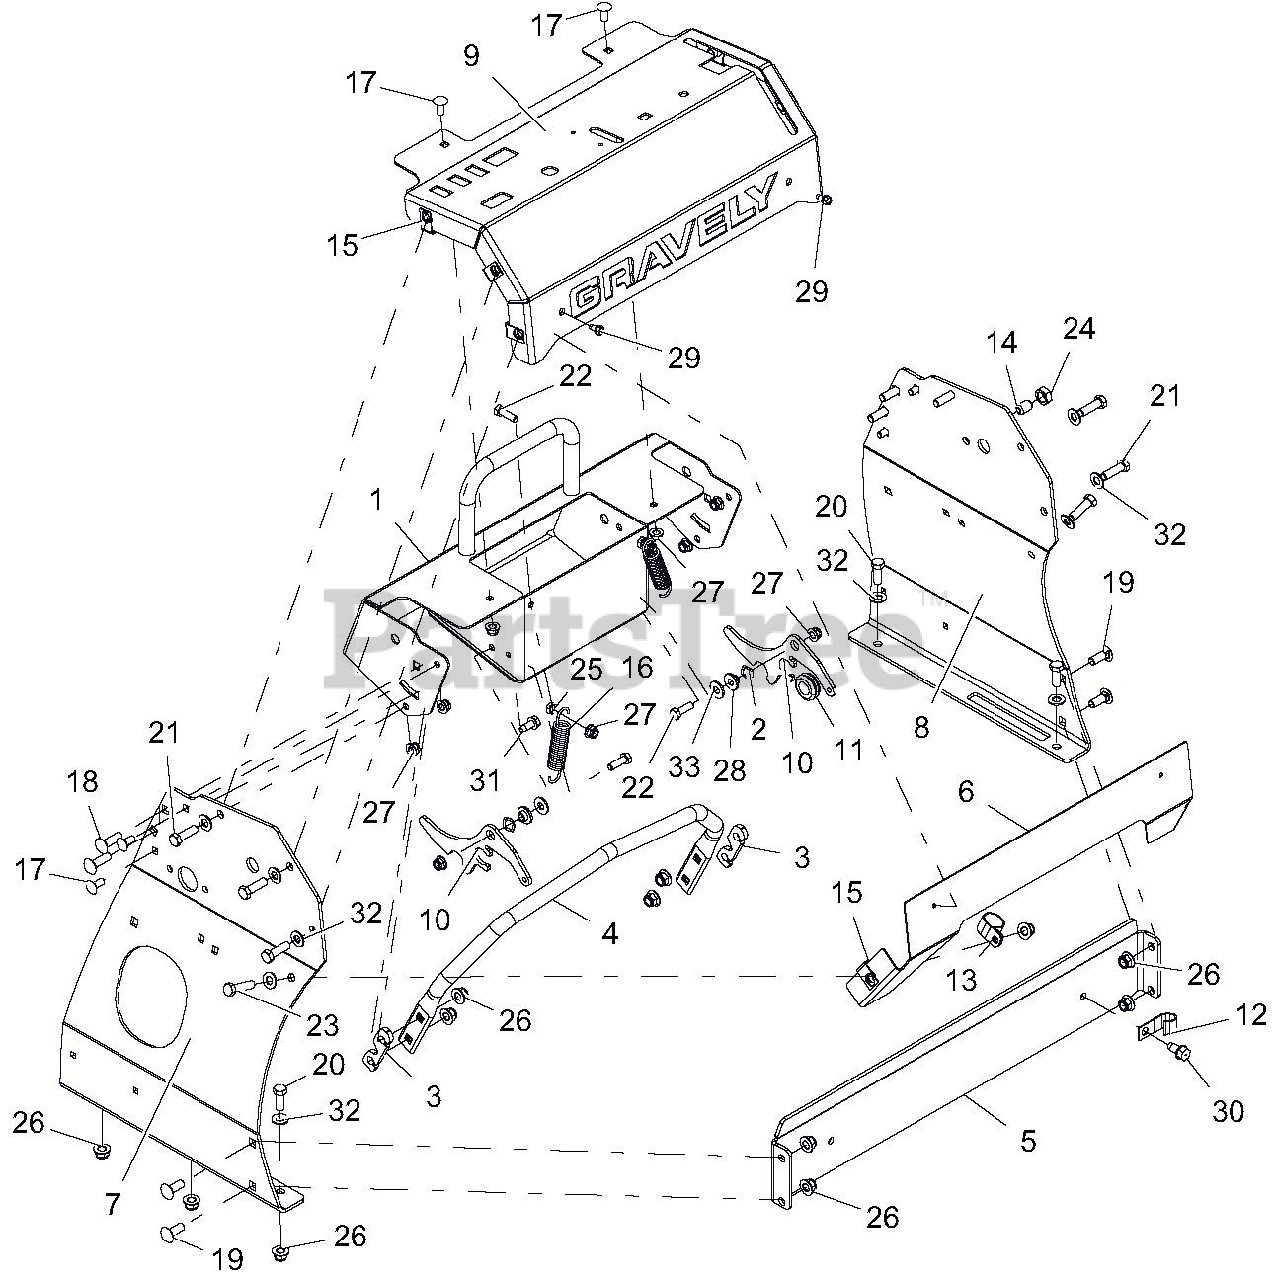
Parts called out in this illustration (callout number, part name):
1	WLDMT, CONTROL PANEL, PRO-STANCE
2	WAVE WASHER .531X.781X.125 FH
3	SHIM, BAR 5 DEG SPEED
4	STOP, FORWARD STEERING
5	STIFFENER, TOWER
6	PLATE, FRONT BACKER
7	PANEL, TOWER RH, PRO-STANCE
8	PANEL, PROSTANCE LH TOWER
9	KIT, SERVICE PROSTANCE DASH
10	LATCH, PAD MOUNT
11	GROMMET, SPLIT RUBBER
13	CLAMP, CUSHIONED STEEL REV
14	BALL SPRING PLUNGER, .500-13
15	NUT, RTNR .375-16X.37
16	SPRG, EXTENSION
17	BLT-RDHDSQNK .31-18X.75 G5 YWZC
18	BLT-RDHDSQNK .38-16X1.25 G5 YWZC
19	BLT-RDHDSQNK .38-16X1.00 G5 YWZC
20	BLT-HEX .38-16X1.00 GR5 YWZC
21	BLT-HEX .38-16X1.25 GR5 YWZC
22	BLT-HEX .31-18X1.00 GR5 YWZC
23	BLT-HEX .38-16X1.50 GR5 YWZC
24	NUT, JAM .500-13 YWZC
25	@NUT-LK-CTR-JAM .31-18 YWZC
26	NUT-LK-NYL-FLG .38-16 YWZC
27	NUT-LK-NYL-FLG .31-18 YWZC
28	BSHG, FLG .32X.500.344X.880
29	SCR-TAP .25-20X.50 HWH TR YWZ
30	SCR-TAP .38-16X.75 HWH TR YWZ
31	SCR-TAP .31-18X.75 HWH TR YWZ
32	WSHR-FL-STL.406X.812X.065 YWZ
33	WSHR-FL-STL.38X.875X.083 YWZC
